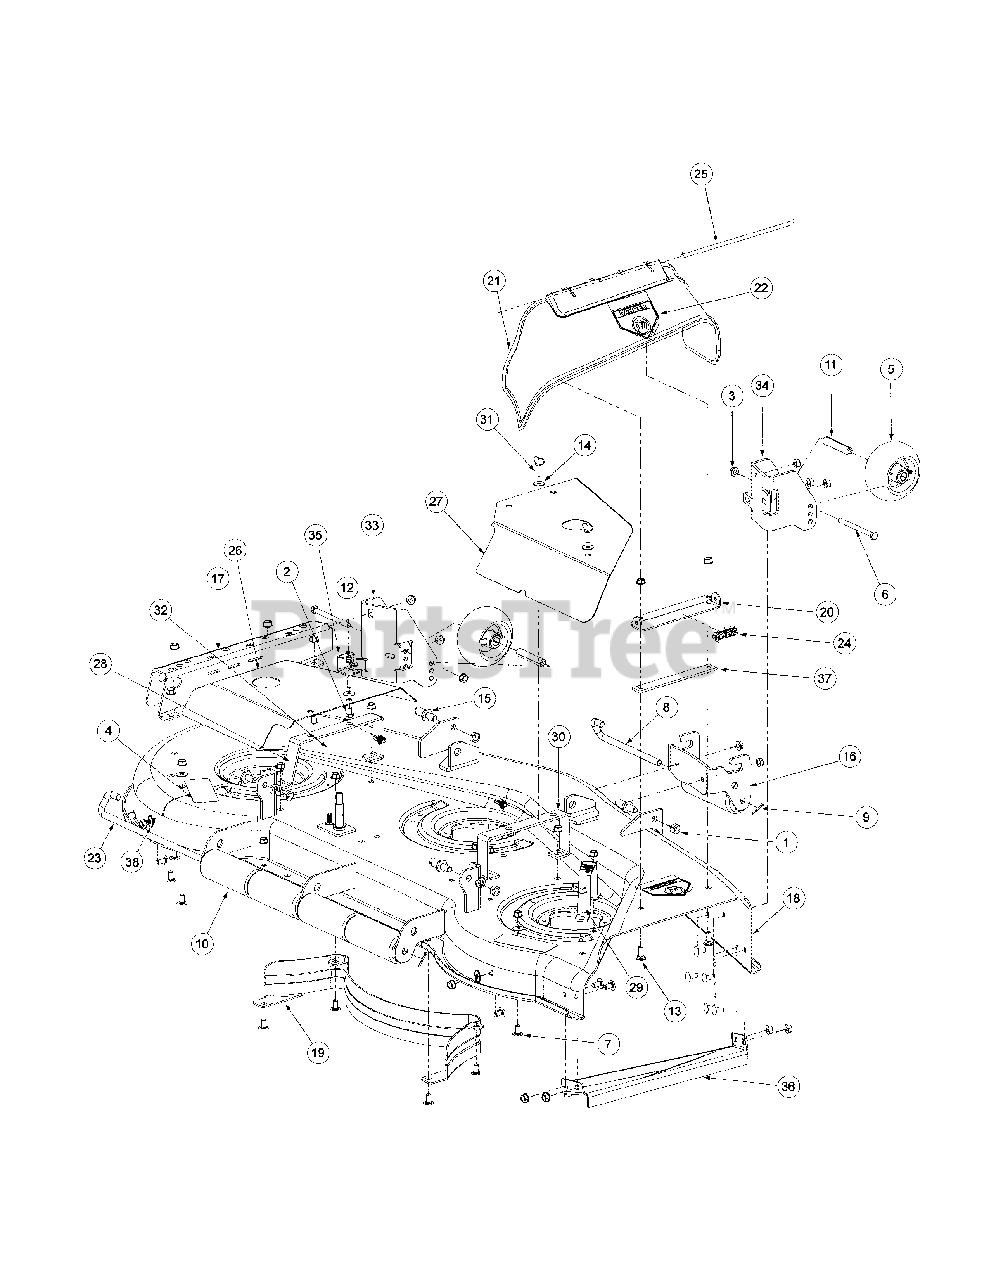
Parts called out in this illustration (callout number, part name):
1	Lock Nut, Nylon Insert, 1/2-13
2	Hex, Cap, Screw, 5/16-18 x 3/4
3	Hex, Nut, Flange Lock 3/8-16
4	Decal, Warning Shield Missing
5	Wheel, Caster, 5.00"
5	Grease Fitting
6	Screw, Hex Cap, 3/8-16 x 4.25"
7	Carriage, Bolt, 3/8-16 x .75 Long
8	Pin, Roller, 1/2 Dia. x 7.31" Long
9	Pin, Cotter, 1/8 x 1.0"
10	Roller, Front
11	Spacer Wheel
12	Lock Nut, Hex Flange 5/16-18
13	Carriage, Bolt, 3/8-16 x 2
14	Washer, Belle, .325 x .930 x .045
15	Pin, 5/8 Diameter x 1.2 Long
16	Front, Roller, Bracket
17	Brace Assembly 60 Deck
18	60 Weldment, Housing Deck
19	Rear, Deck, Baffle,
20	Chute, Bracket Deflector
21	60" Deck, Deflector, Chute
22	Decal, Danger Hands and Feet
23	Roller, Pin
24	Torsion Spring, 0.4 ID x 2.16 Long
25	Chute, Rod, Deflector
26	Belt Cover, Welded, 60 LH
27	Belt Cover, 60 Deck, RH
28	Support Bracket, 60 LH Belt Cover
29	Support Bracket, 60 RH Belt Cover
30	Support Bracket, 60 Center
31	Screw, Thumb, 5/16-18 x 1.0 Long
32	U Nut, 5/16-18
33	Bracket, Deck, Front LH
34	Bracket, Deck, Front, RT
35	Bracket, Stop, Tension Rod
36	Guard Assembly, Toe
37	Spacer, Strip, 0.1875 Thick
38	Washer, Flat, 3/8"
